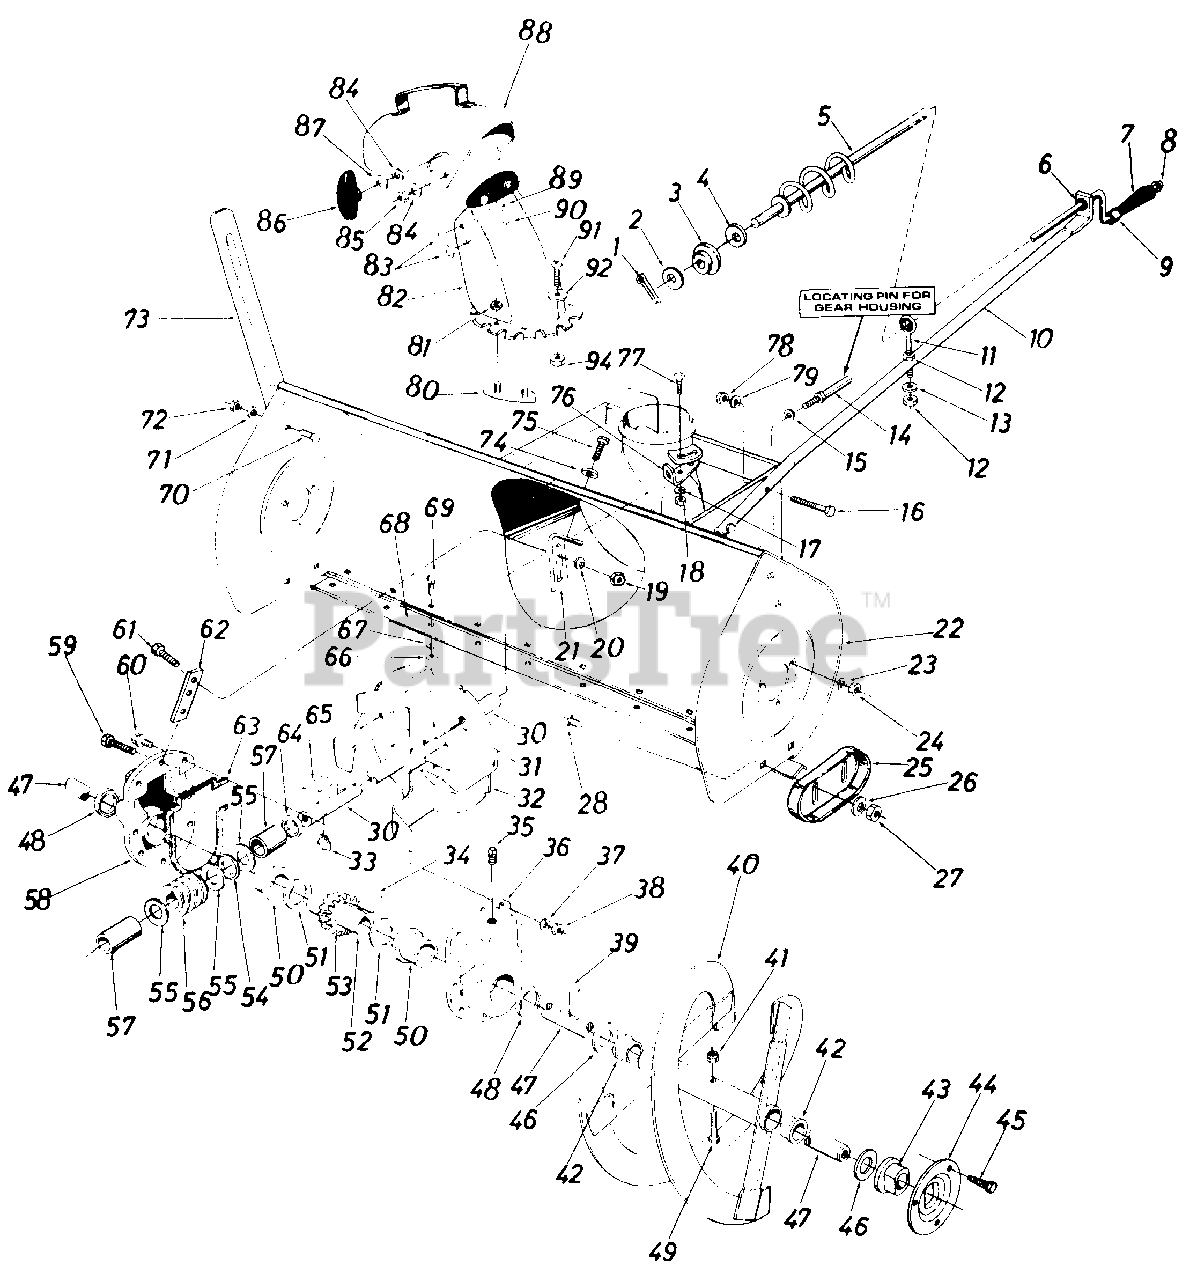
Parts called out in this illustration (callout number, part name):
1	Cotter Pin
2	Fl.-Wash. .39" I.D. x .62" O.D.
3	Plastic Bushina
4	Fl.-Wash. .385r' I.D. x .62" O.D.
5	Chute Cran k Ass'y.
6	Plastic Bushing
7	Knob Ball 3/8 Dia. Hole
8	Push Nut 3/8" Rod
9	Spacer .385 I.D. x .50" I.D.
10	Chute Crank Support Tubing
11	Eyebolt
12	Hex Nut 5/16-18 Thd.
13	Bell .-Wash . .345 " I . D. x .88 " 0. D.
14	Stud 3/8-16 x 2.75" Lg.
15	Bell.-Wash. .400" I.D. x.88" 0. D.
16	Hex Bolt 3/8-24 x 1.25" Lg.
17	Bell.-Wash. .345" I.D. x .88" 0. D.
18	Hex Nut 5/16-18 Thd.
19	Hex Nut 1/4-28 Thd.
20	Bell.-Wash. .265" I.D. x .75" 0. D.
22	45" Snow Blower Housing Ass'y.
23	L.-Wash. 5/16" I.D.
24	Hex Nut 5/16-18 Thd.
25	Slide Shoe
26	Bell.-Wash. .400" I.D. x .88" 0. D.
27	Hex Jam Nut 3/8-16 Thd.
28	Carriage Bolt3/8-16x .62" Lg.
30	Blower Axle .875" Dia. x 14.75" Lg.
31	Spring Pin Spir. 5/16" Dia. x 1.75" Lg.
34	#91 Woodr-Key 1/4 x 3/4" Dia. (HDN)
35	Vent Plug
36	Comp. Gear Hsg. Half-L.H.
37	Spr.-Wash. .32" I.D. x .62" O.D.
38	Hex Ins. L.-Nut 5/16-18 Thd.
39	#91 Woodr-Key 1/4 x 3/4" Dia. (HDN)
41	Hex Ins. L.-Nut 5/16-18 Thd.
42	Plastic Bushing
43	Flange Brg. w/flats 1" I.D.
44	Bearing Housing
45	Hex Sems Bolt 5/16-18 x .75" Lg.
46	Fl.-Wash. 1.00" I.D. x 1.75" O.D.
47	Spiral Axle
48	Flange Bearing 1.503" I.D.
49	Shear Bolt 5/16-18 x 1.75" Lg.
50	Oil Seal 1.50" I.D.
51	FI.-Wash.1.50" I.D. x 2.00" O.D.
52	Worm Gear Shaft
53	Double Threaded Worm Gear-L.H.
54	Thrust Brg.-.88" I.D. x 1.44" 0.D.
55	Fl. Wash. .88" I.D. x 1.4" O.D.
56	Double Threaded Worm-L.H.
57	Sleeve
58	Complete Gear Hsg. Half-R.H.
59	Hex Bolt5/16-18x 1.25" Lg.
60	Hex Bolt 5/16-18 x 1.0" Lg. (Grade 5)
61	Hex Bolt 1/4-28 x .75" Lg.
62	Gear Housing Support Plate
63	Rubber Gasket
64	Oil Seal-.875' I.D.
65	#9 Hi-Pro Key 3/16 x 3/4" Dia. (HT.)
66	Hex Nut 5/16-18 Thd.
67	L.-Wash. 5/16" I.D.
69	Carriage Bolt 5/16-18 x 1.00" Lg.
70	Carriage Bolt 5/16-18 x .62" Lg.
71	L.-Wash. 5/16" I.D.
72	Hex Nut 5/16-18 Thd.
73	Guide Blade
74	Bell.-Wash. .345" I.D. x .88" O.D.
75	Hex Wash. Hd. AB Tap Scr 5/16 x .75" Lg.
77	CarriageBolt5/16-18x.75" Lg.
78	Hex Ins. L.-Nut 3/8-24 Thd.
79	L.-Wash. 3/8" I.D.
80	Chute Flange Keeper
81	Hex Cent. L.-Nut 1/4-20 Thd.
82	Chute Ass'y. w/Chute Guard
83	Fl.-Wash. .285" I.D. x 1.25" O.D.
84	Bell.-Wash. .345" I.D. x .88" O.D.
85	Hex Cent. L.-Nut 5/16-18 Thd.
86	Knob Handle
87	Bell.-Wash. .345" I.D. x .88" O.D.
88	Top Chute Ass'y. I
89	Carriage Bolt 5/16-18 x 1.00" Lg.
90	Carriage Bolt 5/16-18 x .62" Lg
91	Truss l\/lach. Scr. 1/4-20 x .50
92	Fl.-Wash. .285" I.D. x 1.25" O.D.
94	Hex Cent. L-Nut-1/4-20 Thd.
